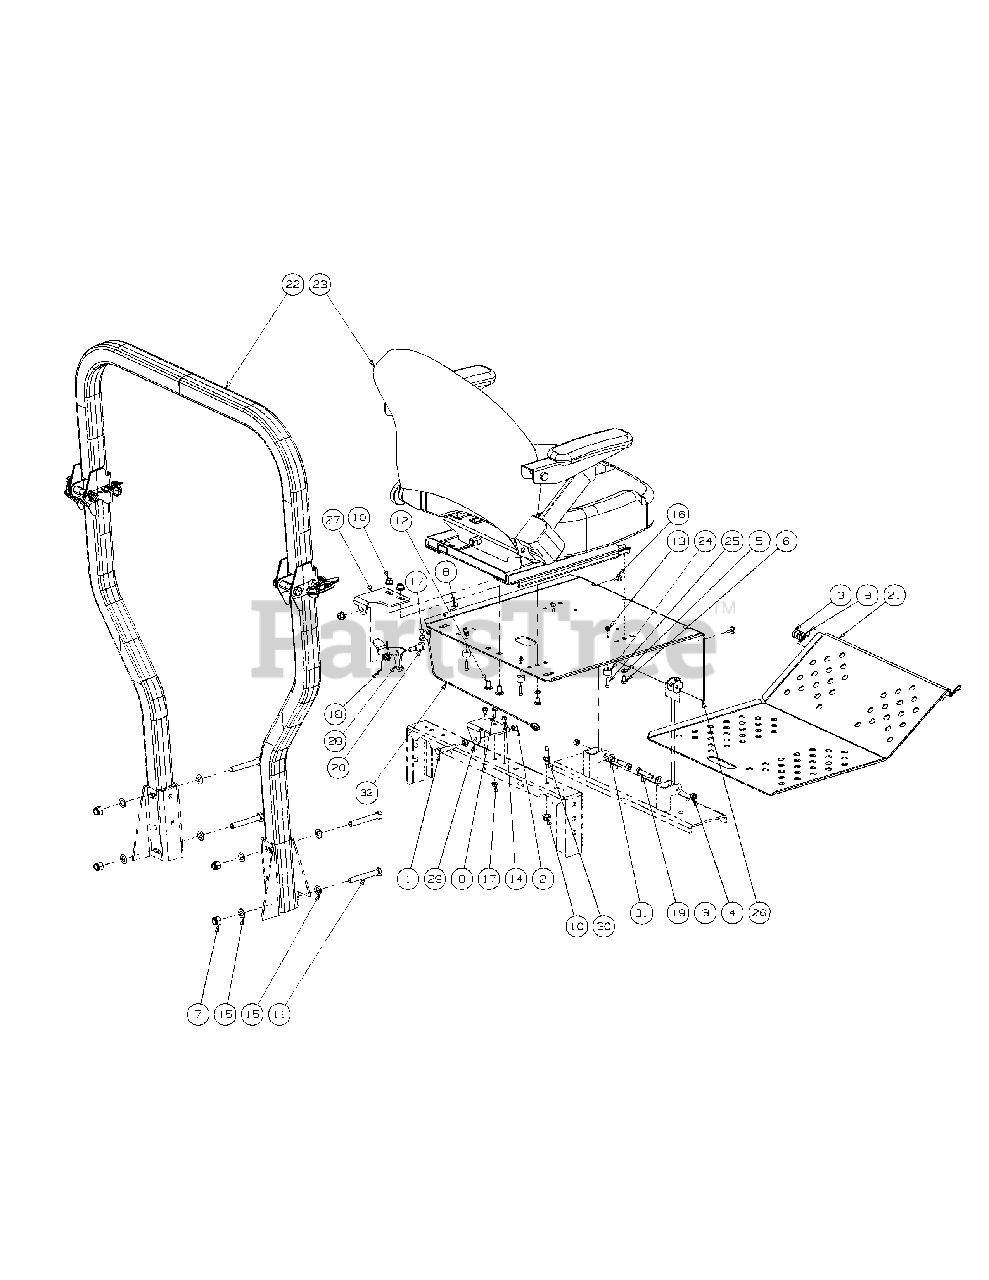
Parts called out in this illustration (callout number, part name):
1	Hex Cap Screw 3/8-16 x 2.00
2	Hex Nut, 3/8-16
4	Flange Lock Nut, 5/16-18
5	Lock Washer, 5/16
6	Hex Cap Screw, 5/16-18 x 1/2
7	Nut, 1/2-13, Nylon Insert
8	Screw, Hex, Cap, 1/4-20 x .75
9	Hair Pin, 3/8-1/2
10	Flange Lock, Hex Nut, 3/8-16
11	Hex Cap Screw, 1/2-13 x 3.50
12	Carriage Bolt, 3/8-16 x .75 Long
13	Nut, #10-24, Nylon Lock
14	Screw, TT, 1/4-20, 0.5, Hex Index Washer
15	Washer, .536 ID x .930 OD x .05
16	Rubber Bumper, .62 OD x .22 Thick
17	Lock Nut, 1/4-20
18	Deck Lift Spring, Left Hand
19	Shoulder Bolt, .375 x 1.50
20	Shoulder Bolt, 1/2 x 3/4, 3/8-16
21	Floor Panel Assembly
22	Foldable Rops Assembly includes:
23	Seat w/ Seat Belt & Suspension
24	Rubber Stop with Washer
25	Standard Cap Screw, #10-24 x .75
26	Seat Plate Assembly
27	Seat Latch Bracket
28	Latch Lever Bracket
29	Latch Bracket
30	Adjustable Stud
31	Flat Washer, .406 ID, 1.0 OD, .105
32	Cable Support
